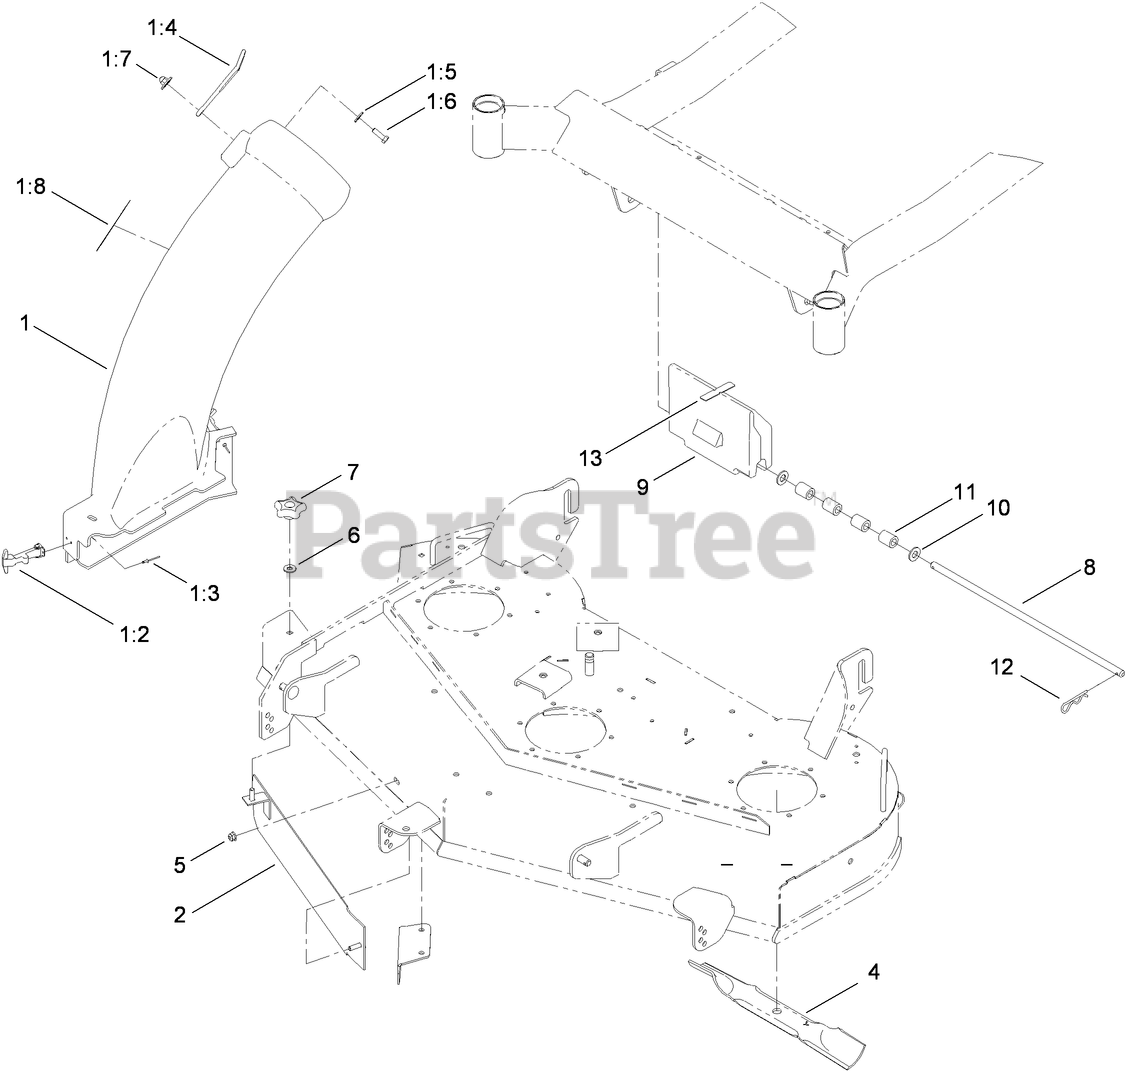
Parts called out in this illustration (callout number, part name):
1	48 INCH BAGGER CHUTE ASM
1:2	HANDLE ASM
1:3	RIVET-POP
1:4	RETAINER-DUCT
1:5	WASHER-FLAT
1:6	SCREW-HH
1:7	NUT-IMPELLER
1:8	DECAL-DANGER
4	BLADE-HI LIFT, 16.50 IN
5	NUT-HF, NI
6	WASHER-FLAT
7	KNOB-LOCKING
8	ROD-DECK, PIVOT
9	WEIGHT-BAGGER
10	WASHER-FLAT
11	SPACER-WHEEL
12	PIN-HAIR
13	BUMPER-PAD
